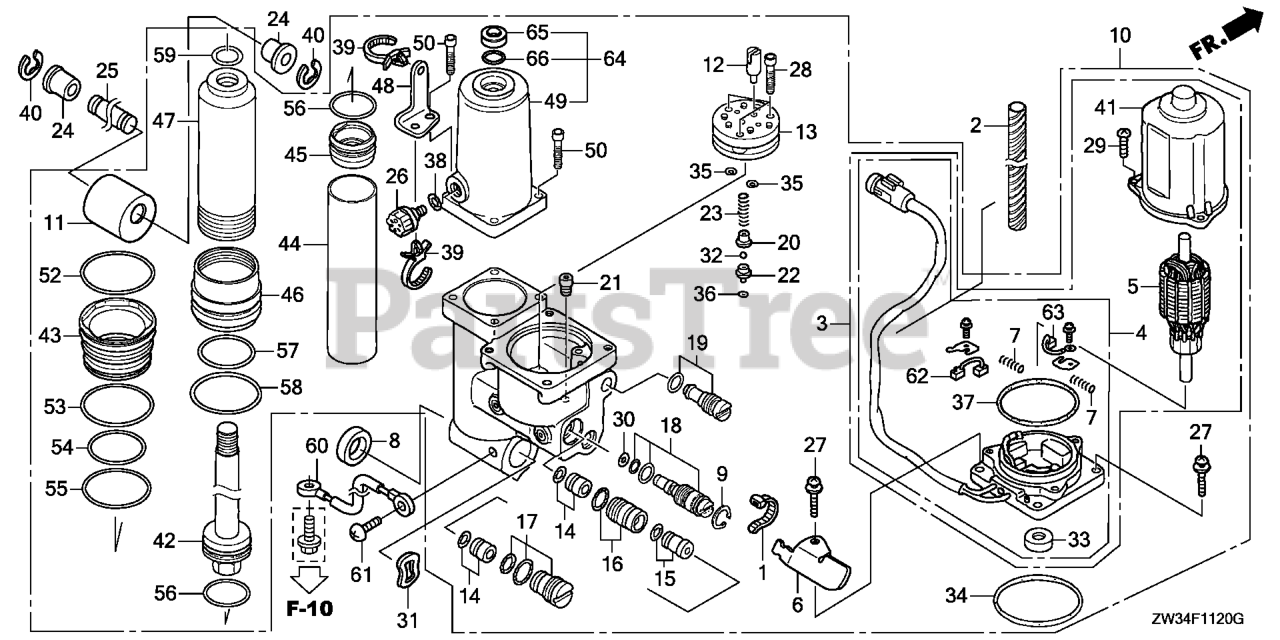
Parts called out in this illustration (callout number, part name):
1	BAND (BLACK 3.5X140)
2	TUBE, SPIRAL
3	MOTOR ASSY., POWER TILT
4	BRACKET ASSY.
6	CLAMP, WIRE
7	SPRING, MOTOR
8	SPACER (19.4X6)
9	CIRCLIP (INNER) (16)
10	TRIM-TILT ASSY., POWER
11	METAL, JOINT
12	JOINT, DRIVE
18	VALVE, MANUAL
20	GUIDE, SPRING
21	VALVE, SET
22	SEAT B, VALVE
23	SPRING, VALVE
24	BUSH, CYLINDER (UPPER)
25	PIN, CYLINDER (UPPER)
26	CAP, OIL TANK
27	SCREW-WASHER
28	BOLT B, SOCKET
29	SCREW, PAN (5X20)
30	WASHER, SEAL
31	WASHER, WAVE (26MM)
32	BALL, STEEL
34	O-RING (1.8X69.6)
35	O-RING (1.5X6.5)
36	O-RING (1.5X3.5)
37	O-RING
38	O-RING (1.8X10.8)
39	CLIP, HARNESS BAND (145MM) (BLACK)
40	E-RING (10MM)
42	ROD, PISTON
43	GUIDE, TUBE (OUTER)
45	PISTON, FREE
46	LOWER TILT CYLINDER
47	TUBE (OUTER)
48	PLATE, SET
50	BOLT, SOCKET (5X0.8)
51	SEAL, WATER
52	O-RING (2.0X52.5)
53	O-RING (2.0X49.5)
54	O-RING (2.4X41.2)
55	O-RING (2.0X45.5)
56	O-RING (2.0X28.5)
57	O-RING (2.0X34.5)
58	O-RING (3.5X41.7)
59	O-RING (2.4X15.8)
60	WIRE, LEAD (1.5X116MM)
61	SCREW, PAN (6X8)
62	BREAKER ASSY.
63	BRUSH ASSY.
65	SEAL, WATER
66	O-RING (1.9X15.8)
